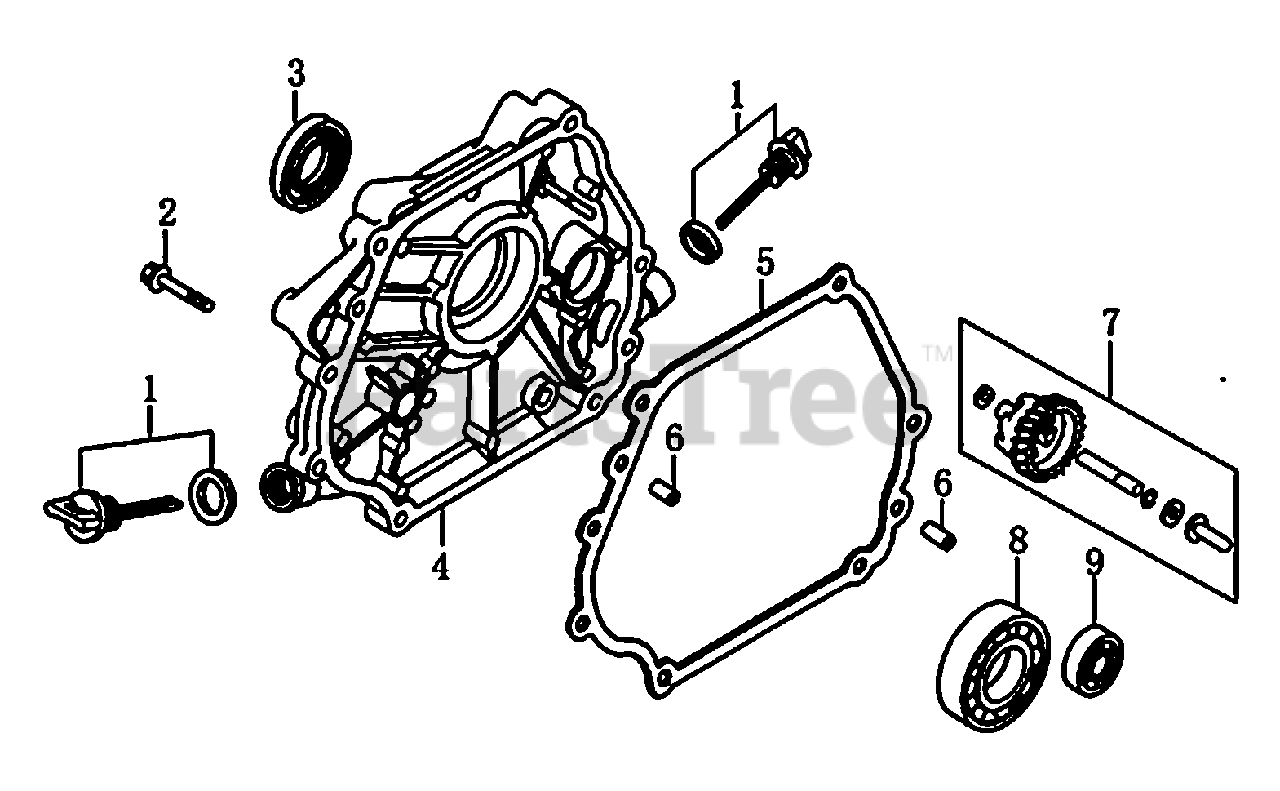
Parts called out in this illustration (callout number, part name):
1	DIPSTICK W/WASHER
2	BOLT, FLANGE 8X40
3	SEAL, OIL 35X52X7
4	COVER, CRANKCASE
5	GASKET,CRANKCASE COVER
6	DOWEL PIN 8X12
7	GOVERNOR ASSY.
8	BEARING, BALL 6207
9	BEARING, BALL 6202
